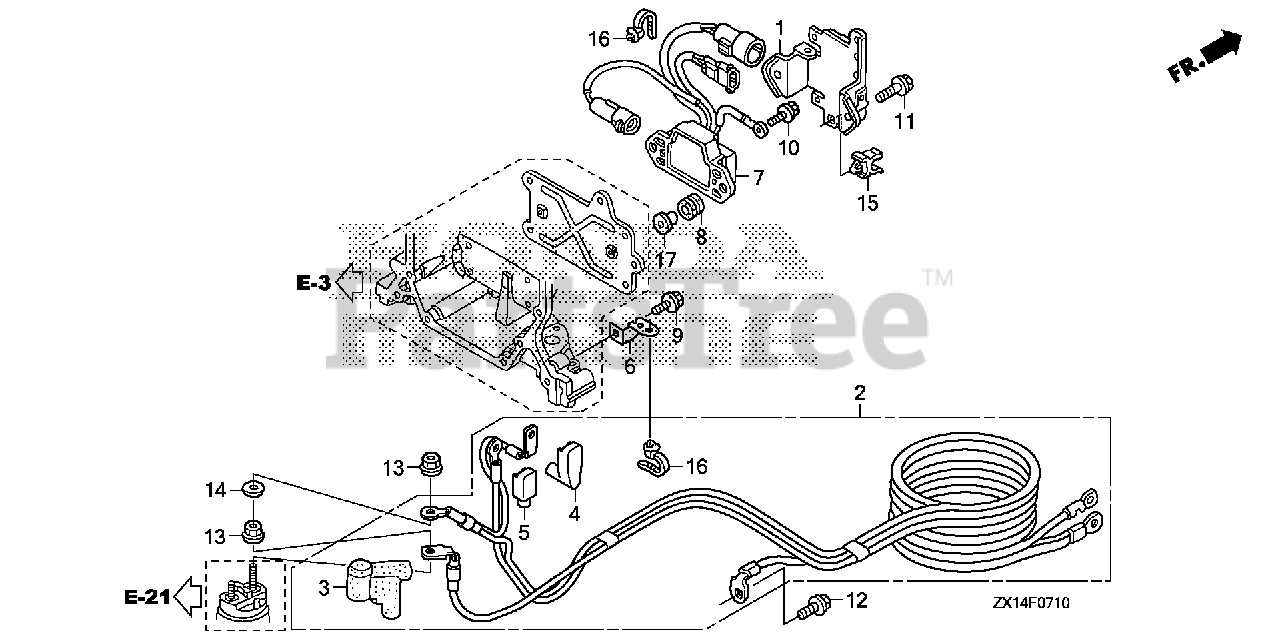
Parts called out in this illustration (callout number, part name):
1	BRACKET A, CONNECTOR
2	CABLE ASSY., STARTER
3	COVER, STARTER TERMINAL
4	COVER B, TERMINAL (L)
5	COVER B, TERMINAL
6	BRACKET B, CABLE
7	RELAY ASSY., POWER TILT
8	GROMMET, RELAY
9	BOLT, FLANGE (6X14) (CT200)
10	BOLT, FLANGE (6X12)
11	BOLT, FLANGE (6X22)
12	BOLT, FLANGE (8X18)
13	NUT-WASHER (8MM)
14	WASHER, PLAIN (8MM)
15	CLIP, FUEL TUBE (14) (NOT AVAILABLE)
16	CLIP, HARNESS BAND (145MM) (BLACK)
17	COLLAR, MODULE IGNITION CONTROL CASE (CDI)
